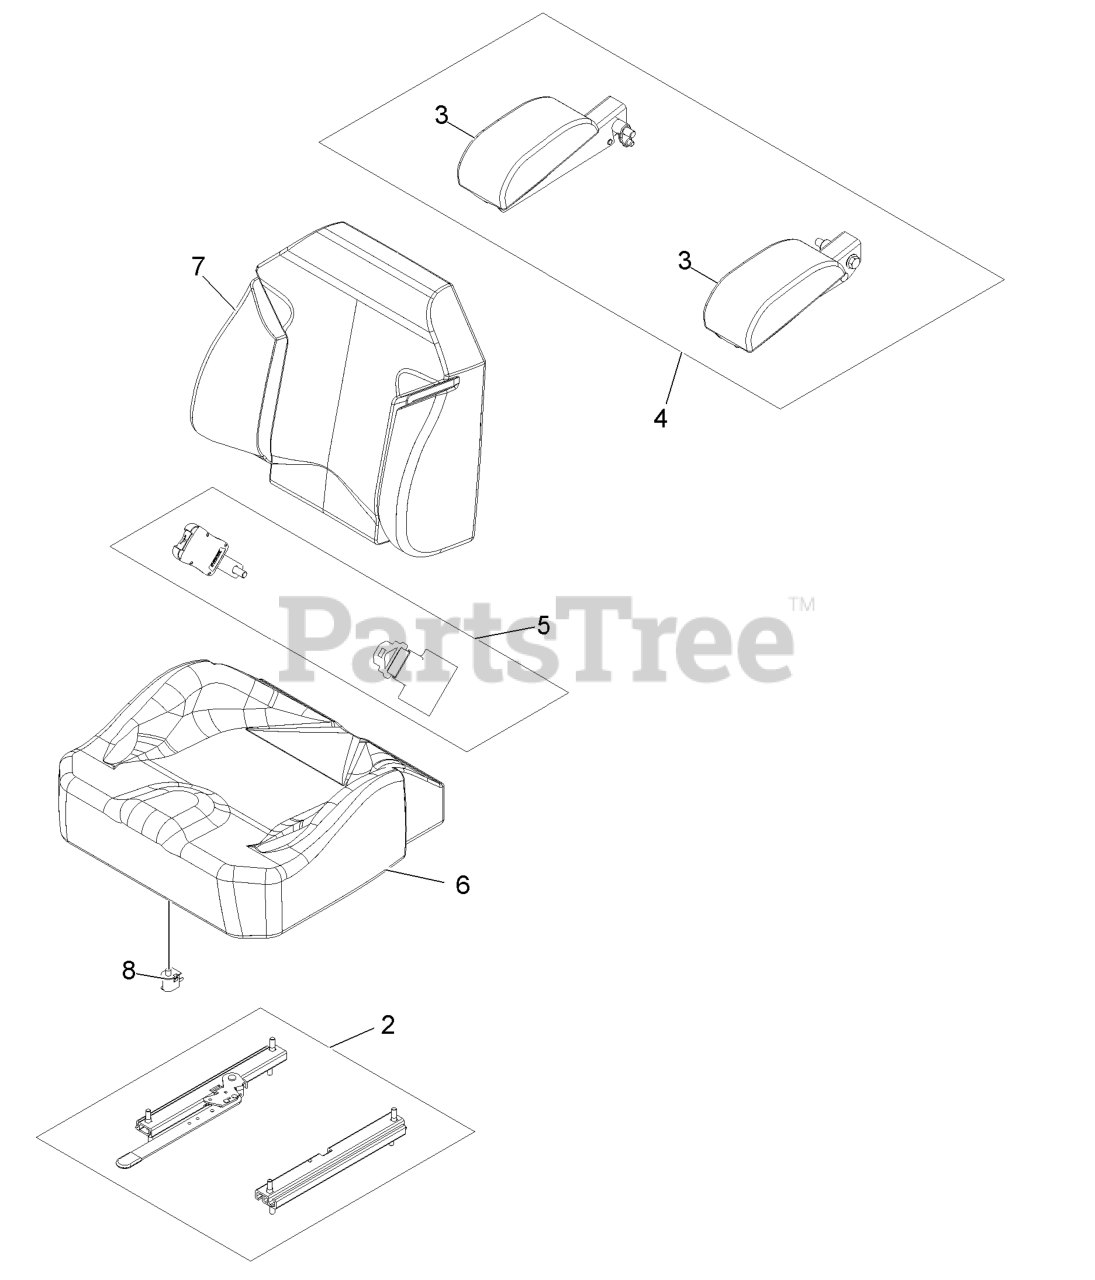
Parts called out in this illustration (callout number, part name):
2	SEAT TRACK SET
3	ARM REST PAD SET
4	ARM REST SET
5	SEAT BELT KIT
6	COVER,CUSHION
7	COVER,BACK
8	SWITCH-BAIL
